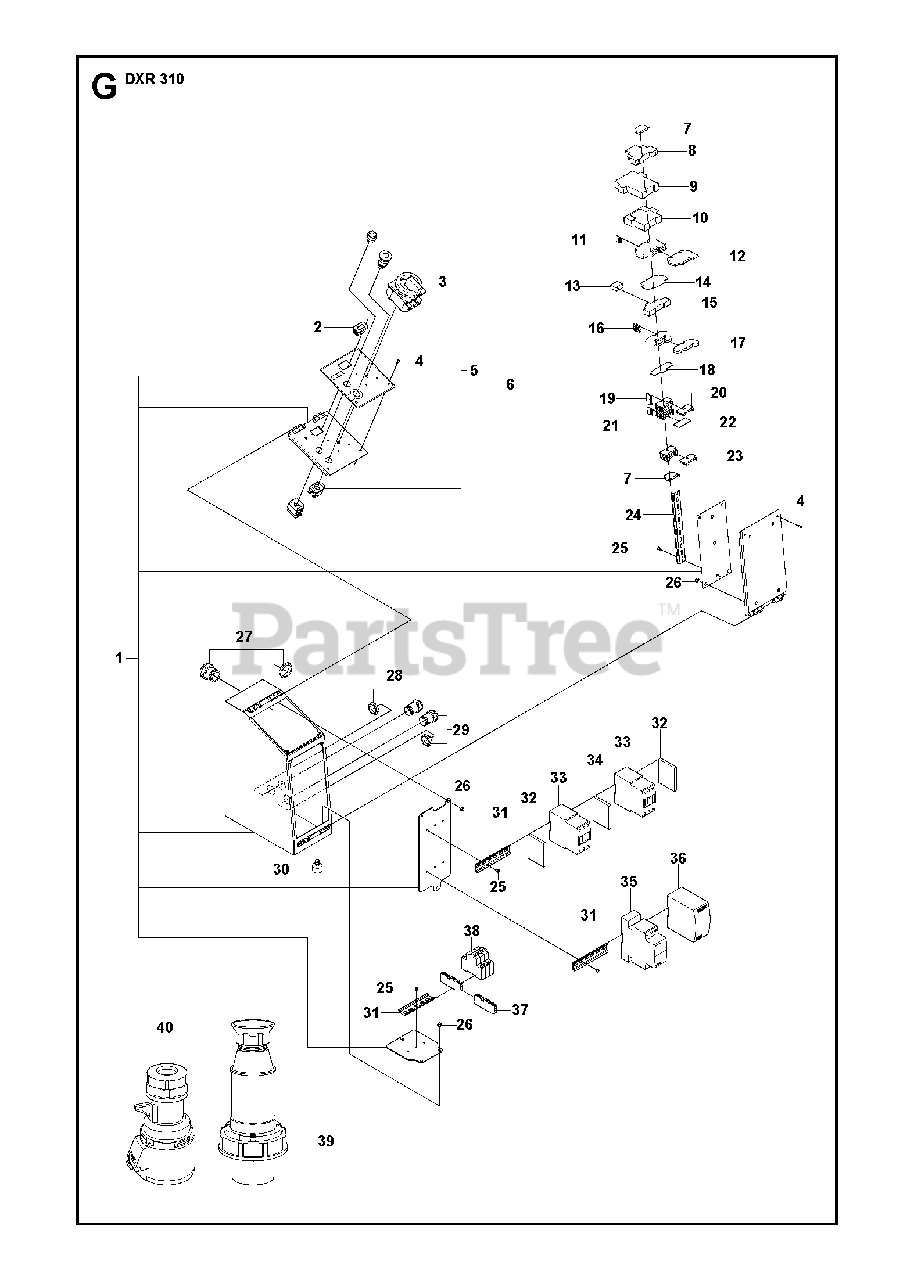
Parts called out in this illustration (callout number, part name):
8	CONTROLT3, Fan control relay
9	RELAYB1, Safety relay
10	RELAYK1, Phase sequence relay
25	SCREW SLPANM
